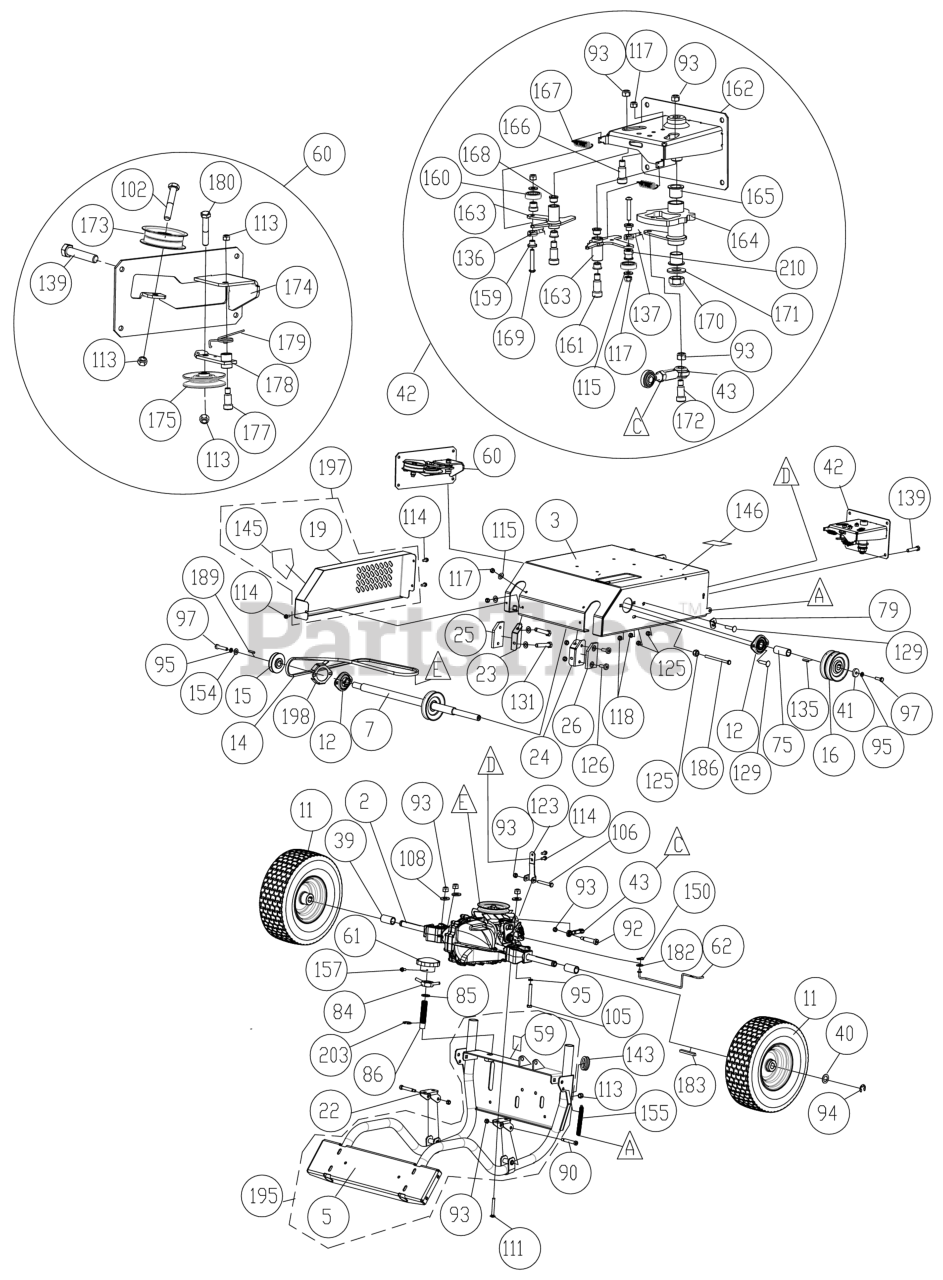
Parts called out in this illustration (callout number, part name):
2	TRANSAXLE
3	ENGINE BASE WA
5	FRAME SUPPORT OS900SP WA
7	JACKSHAFT WA
11	REAR WHEEL13" X 5" PNEU ASSY
12	BEARING & FLANGETTE ASSY .75"
14	BELT, TRUFLEX OS9 SERIES DRIVE
15	PULLEY 0.75 I.D. X 3.50
16	PULLEY 0.75" ID X 4" 4L SECTION
19	GUARD DRIVE BELT
22	BRACKET FIXED FRONT FRAME
23	BRACKET RH WEAR PAD
24	BRACKET LH WEAR PAD
25	WEAR PAD RH
26	WEAR PAD LH
39	SPACER REAR WHEEL
40	WASHER .765" ID X 1.25 OD X .06"
41	WASHER 1.125 OD X 0.344 ID X .25 THK ZP
42	SPEED CONTROL ASSY
43	CONNECTOR SPEED CONTROL
59	LABEL DEPTH GAUGE
60	MULE ASSY OS901SP
61	KNOB HAND
62	ROD, BYPASS ARM TRANSAXLE
75	SPACER PULLEY JACKSHAFT
79	BRACKET CLUTCH CABLE
84	LOCKNUT WA
85	WASHER 3\4" NYLON
86	STUD 3/4"-10 X 3 3/4 PLTD
90	BOLT SHOULDER 3/8" X 2"
92	BOLT SHOULDER 3/8" X 1/2"
93	NUT LOCK 5/16"-18 HEX Z/P
94	RING RETAINING "E" 3/4"
95	WASHER LOCK 5/16 ST MED
97	SCREWCAP 5/16"-24 X 1" GR.8 ZP W/PATCH
102	SCREWCAP 3/8"-16 X 1 3/4" HCS ZP
105	SCREWCAP 5/16"-18 X 3" HCS ZP
106	SCREWCAP 5/16"-18X2" HCS ZP
108	WASHER 5/16" FLATWASHER Z/P
111	BOLT CARRISGE 5/16-18 X 2 3/4" ZP
113	NUT LOCK 3/8"-16 HEX
114	SCREW SELF TAP 1/4"-20 X 5/8" HWH TYPE F
115	WASHER 1/4"SAE9/32"X5/8"X1/16"
116	WASHER 3/8"SAE 13/32"X13/16"X1/16"
117	NUT LOCK 1/4"-20 HEX Z/P
118	NUT FLANGE 5/16"-18 ZP
123	BRACKET TORQUE LIMITING
125	NUT FLANGE 5/16"-18 ZP
126	SCREW SPOT WELD 5/16"-18 X 3/4 W/PROJ
129	BOLT CARRIAGE 5/16"-18 X 3/4" ZP
131	SCREWCAP 1/4"-20 X 1" HCS ZP
135	KEY 3/16" SQ X 1 1/4"
136	SEE: 351219-S
137	SEE: 351271-S
139	SER HEX WASHER FLNG SCREW 5/16"-18 X 3/4"
143	GROMMET 1.25" HOLE
146	LABEL DRIVE RELEASE
150	PIN CLIP HITCH 0.051 X 3/4"
153	NUT LOCK 5/16"-18 LT WT TH ZP
154	WASHER FLAT FENDER 5/16
155	SPRING LIFT ASSIST
157	SCREW MACHINE #10-24 X 2" HWF ZP
159	SPACER, SPEED CONTROL EYELET PM
160	BEARING 1/2" ID X 1.125 OD
161	BOLT SHOULDER 3/8" X 1 3/4"
162	BRACKET SPEED CONTROL WA
163	BELLCRANK SPEED CONTROL WA
164	CAM SPEED CONTROL WA
165	BUSHING PIVOT FRAME AE
166	BOLT SHOULDER 5/16" X 1 1/2"
167	SPRING EXTENSION
168	BUSHING 3/8 ID X 1/2 OD X 3/8
169	SCREWCAP 1/4-20 X 1 3/4 SKT BUT HD
170	NUT LOCK 5/8"-11 LT WT TH Z/P
171	WASHER FLAT 5/8" SAE ZP
172	SCREWCAP 5/16"-18 X 1" HCS ZP
173	PULLEY IDLER 2.75" OD X 3/8" BORE
174	BRACKET DRIVE BELT WA
175	PULLEY 3V GROOVE IDLER
177	BOLT SHOULDER 1/2" X 2"
178	ARM IDLER MULE DRIVE WA OS900SP
179	SPRING, IDLER MULE DRIVE
180	SCREWCAP 3/8" - 16 X 1/2" HCS ZP
182	WASHER #10SAE 7/32"X1/2"X1/16"
183	KEY 3/16" SQ X 2 1/8"
186	SCREWCAP 5/16"-18 X 5" HCS ZP
189	KEY 3/16" SQ X 5/8"
195	FRAME SUPPORT OS901SP W/LABELS
197	DRIVE BELT GUARD WA W/LABELS
198	BRACKET, BELT GUIDE OS901SP
203	RING SNAP TRUARC 5/8"
210	SPACER. SPEED CONTROL STEPPED PM
